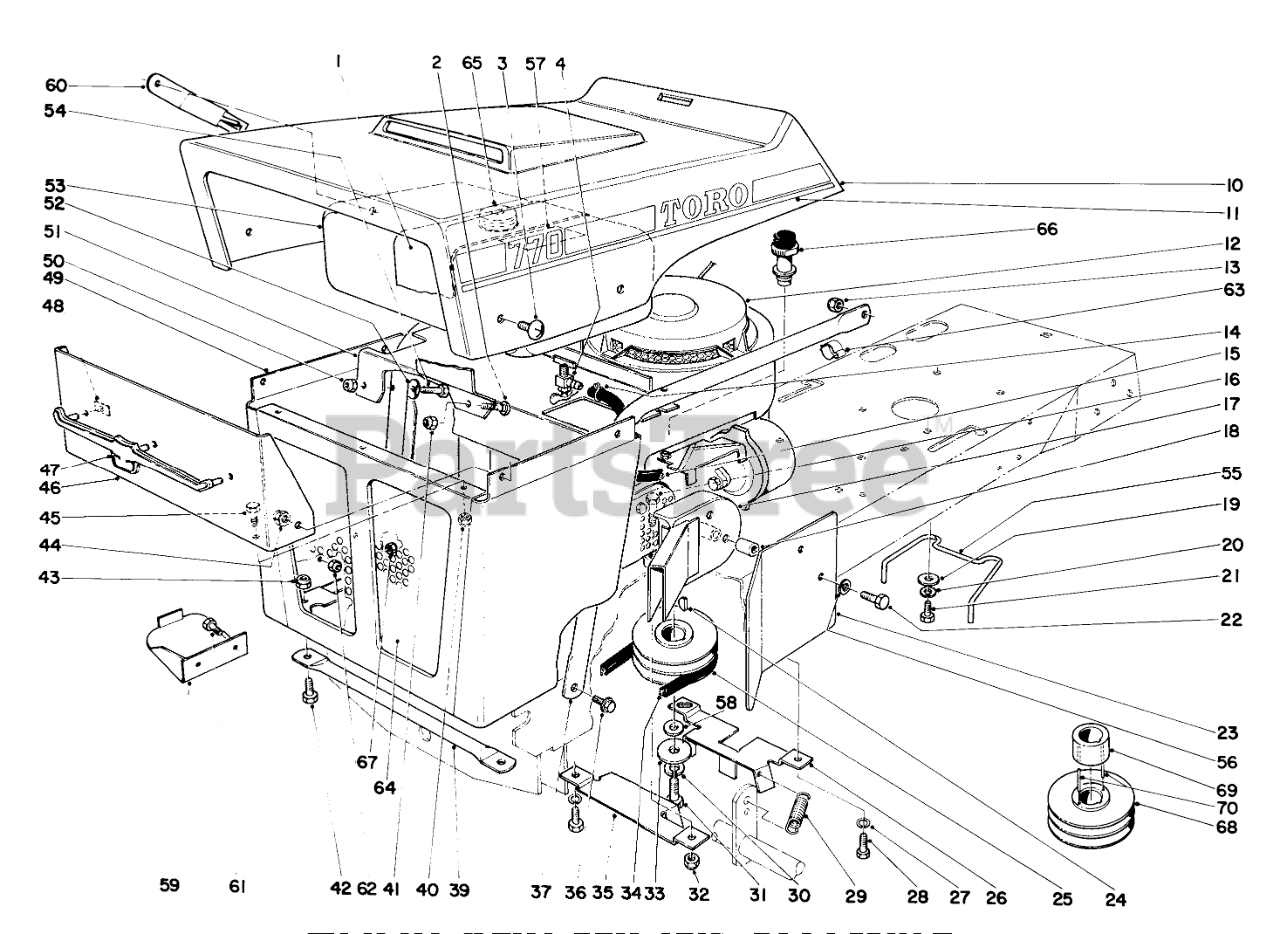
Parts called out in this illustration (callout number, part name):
1	Strap Gas Tank
2	BOLT-CARR
3	Truss Head Screw
4	Hose Fitting
11	Decal Hood L. H. (Recoil)
12	Engine (Recoil)
14	CLAMP-HOSE
16	SCREW-HH
17	Muffler Baffle
18	Spacer Muffler
19	WASHER-PLAIN
20	WASHER-LOCK/SP
21	SCREW-HH
22	SCREW-HH
23	Heat Shield Muffler
24	KEY-WOODRUFF
25	Engine Pulley
26	Belt Guide
27	WASHER-LOCK/SP
28	SCREW-HH
29	Spring
30	WASHER-LOCK
31	SCREW-HH
32	Nut
33	Washer
34	ENGINE BELT
35	Belt Guide
36	1/4-20X5/8 THDG SEMS
37	Support Gas Tank L. H.
39	Rod Grille Mount
41	Nut
42	SCREW-HH
44	Nut
45	SCREW-HH
46	Grille Panel
47	Bullshead
48	Timmerman Nut
49	Grille Assembly (Recoil)
51	Bracket Gas Tank
52	WASHER
53	Gas Tank
54	SCREW-HH
55	Belt Retainer
56	WASHER-LOCK/SP
57	Decal
58	WASHER-FLAT
59	Trimmer Support
60	Clip Trimmer
61	SCREW-HH
62	NUT-LOCK, CONE
63	CONTROL WIRE CLIP
64	Grille Panel
65	GAS CAP
66	Oil Minder (Recoil)
67	NUT-LOCK, NI
68	Engine Pulley used on Model #57204-000451 thru 000877
69	Adapter used on Model #57204-000451 thru 000877
70	PIN-SPRING
